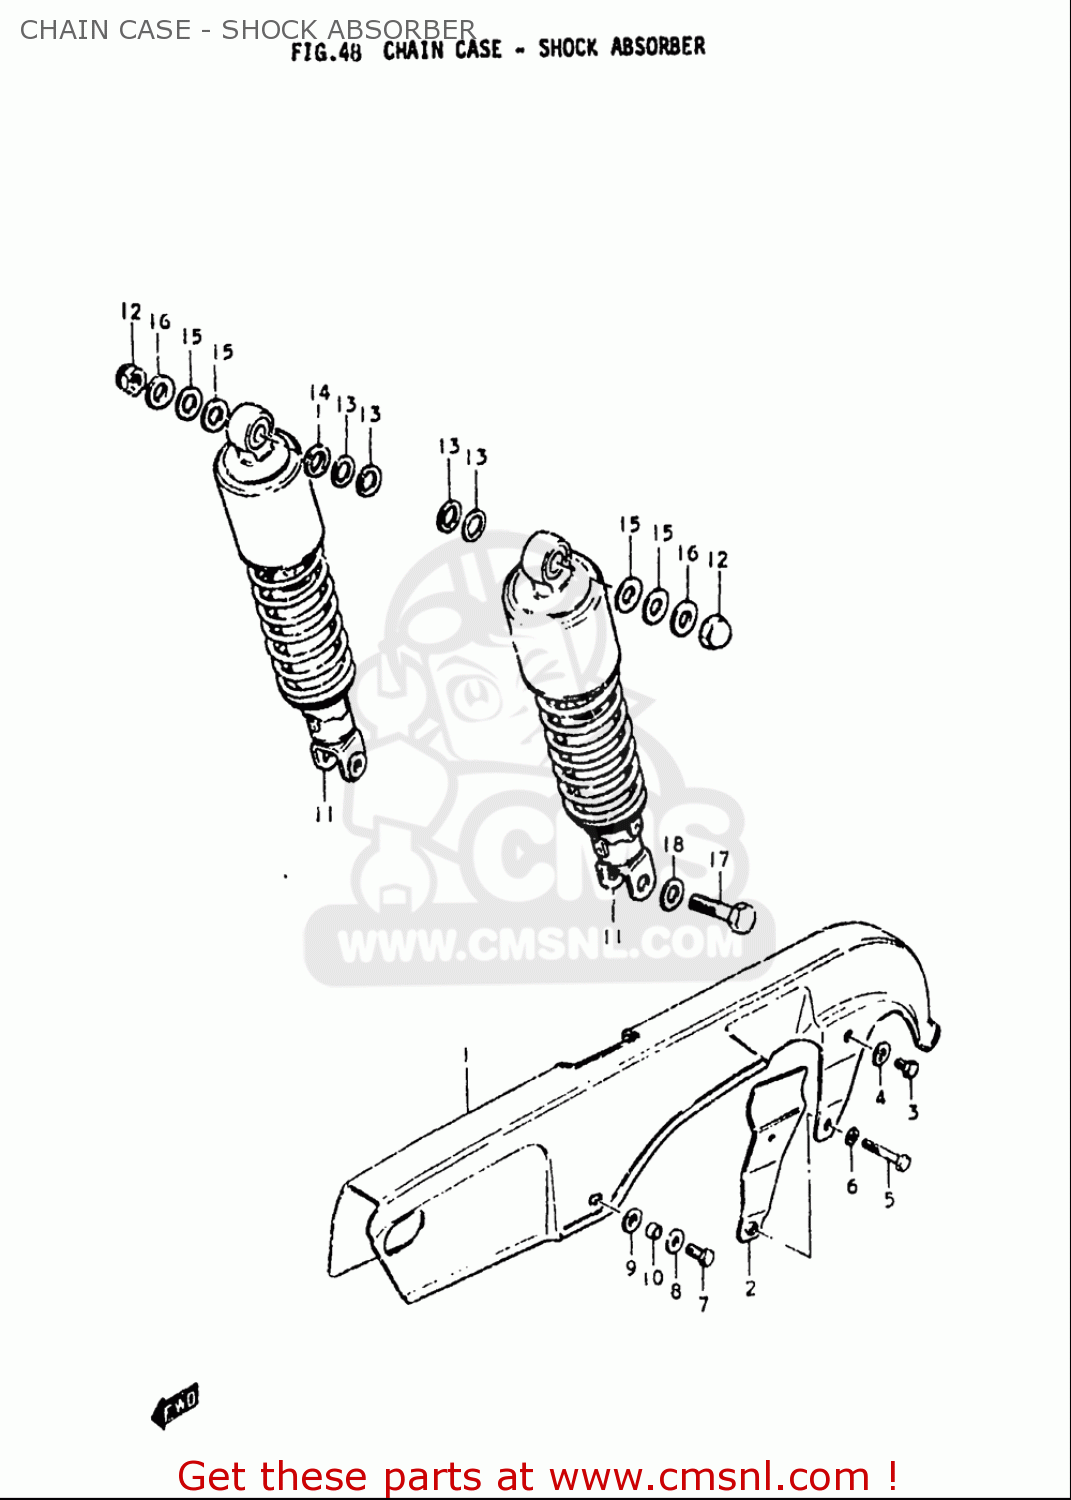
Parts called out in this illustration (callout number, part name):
1	CASE,CHAIN
2	REINFORCEMENT,CHAIN CASE
3	BOLT(6X8)
4	WASHER
5	BOLT
6	WASHER,LOCK
7	BOLT
8	WASHER(6.5X18X1)
9	WASHER(8X14X3)
10	SPACER(6.1X8X5.2)
11	ABSORBER ASSY,RR SHOCK
12	NUT
13	WASHER
14	WASHER(12.5X24X3.2)
15	WASHER (10.5X24X2.3)
16	WASHER (10.5X25X3.2)
17	BOLT(10X36)
18	WASHER
